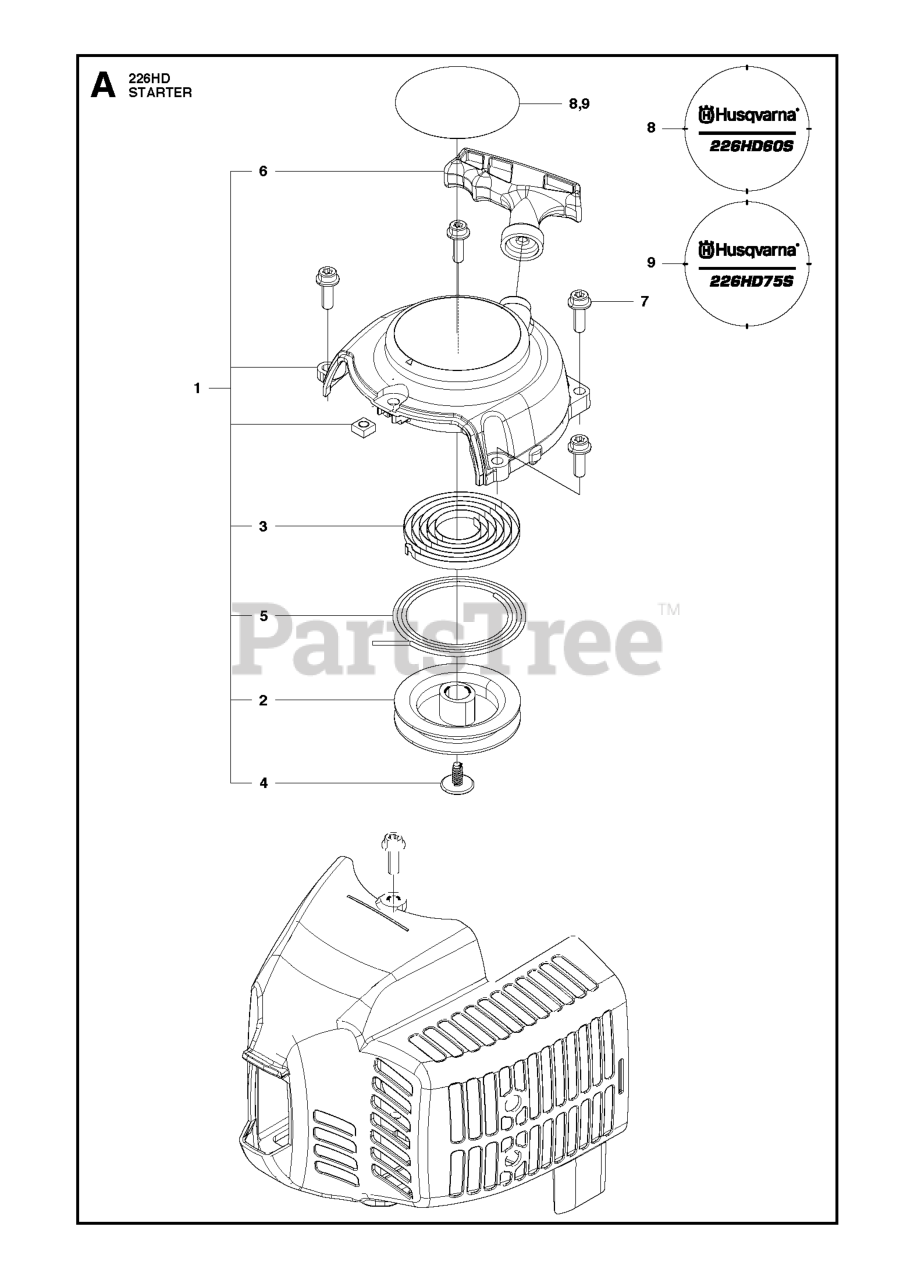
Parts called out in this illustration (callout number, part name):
1	RECOIL ASSY
4	SCREW
9	LABEL, RECOIL
